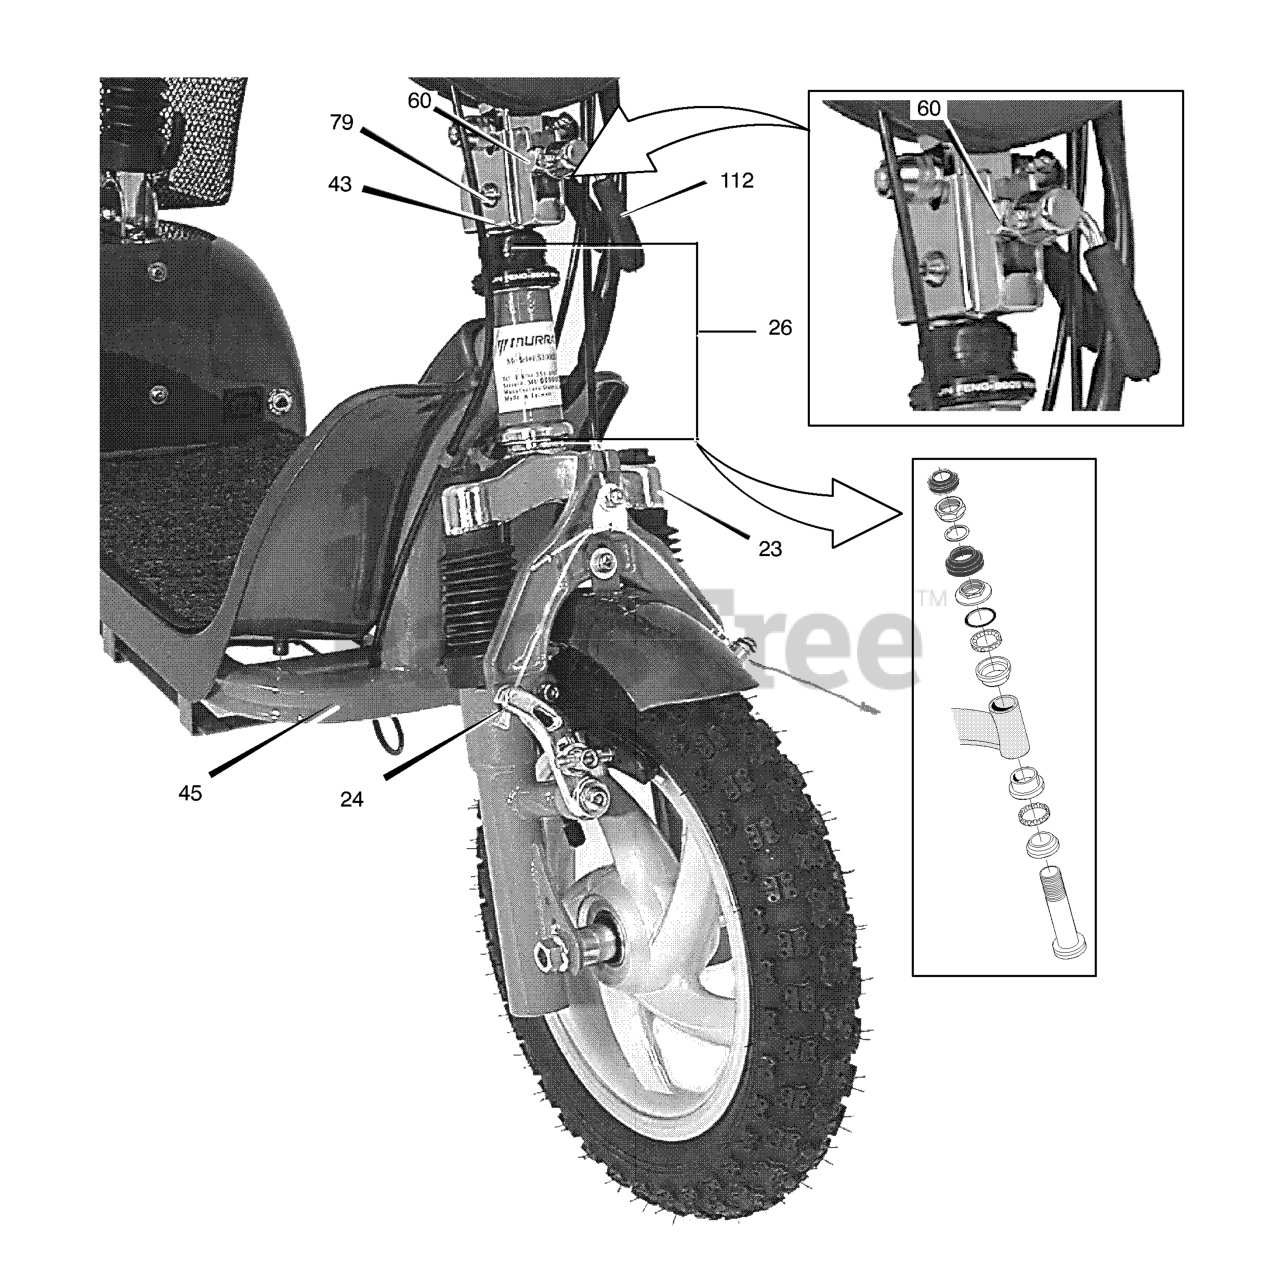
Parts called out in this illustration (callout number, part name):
23	Fork, Front Suspension
24	Brake Assembly, Front
26	Head Set, Front
43	Stem, Handlebar Mounting
45	Frame-RED
60	Stop Bar, Quick Release
79	Screw, Pivot
112	Lever Assembly, Quick Release -Front H'bar Locking Device
